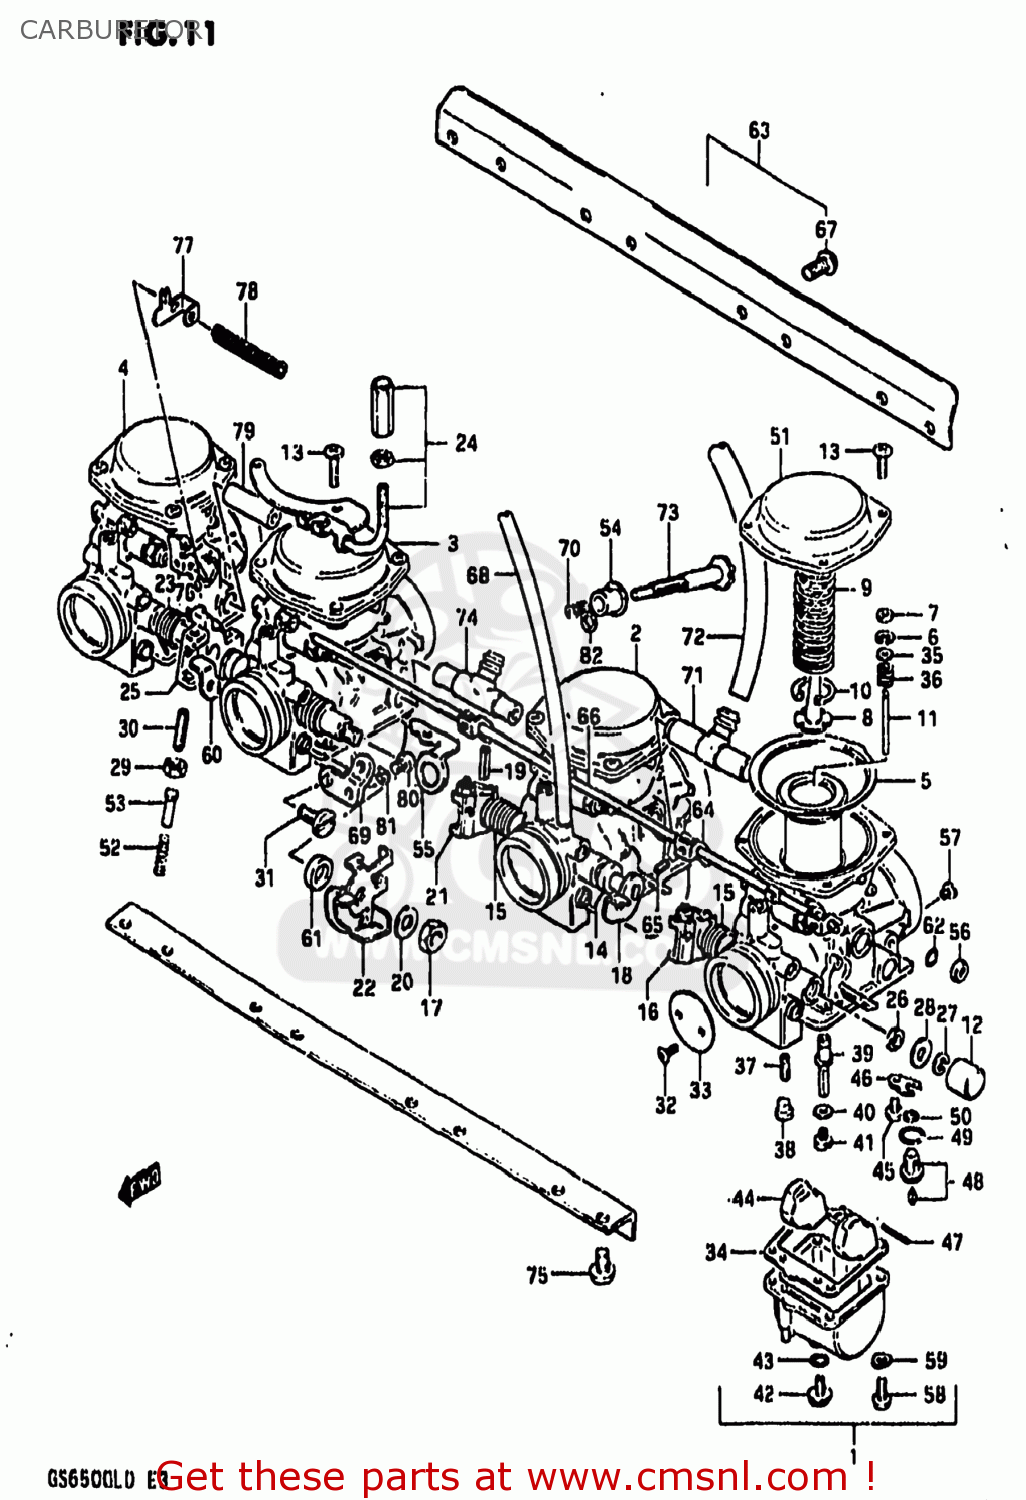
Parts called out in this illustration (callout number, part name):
1	CARBURETOR ASSEMBLY,LEFT
2	CARBURETOR ASSEMBLY
3	CARBURETOR ASSEMBLY
4	CARBURETOR ASSEMBLY
5	DIAPHRAGM
6	CLIP,NEEDLE
7	RING
8	HOLDER,GUIDE
9	SPRING
10	E RING
11	NEEDLE JET
12	CAP
13	SCREW
14	GASKET,THROTTLE SHAFT (NAS)
15	SPRING,THROTTLE SHAFT
16	SHAFT,THROTTLE
17	NUT 8MM
18	SHAFT,THROTTLE
19	PIN,THROTTLE SHAFT
20	WASHER
21	LEVER,THROTTLE SHAFT
22	LEVER ASSEMBLY,THROTTLE
23	SPRING,THROTTLE SHAFT
24	BRACKET,THROTTLE CABLE
25	SHAFT,THROTTLE
26	SEAL
27	E RING
28	GASKET,THROTTLE SHAFT (NAS)
29	NUT
30	SCREW
31	SCREW
32	SCREW
33	VALVE,THROTTLE (BUTTERFLY)
34	GASKET,FLOAT CHAMBER (NAS)
35	WASHER
36	SPRING
37	JET,PILOT(42.5)
38	PLUG,NEEDLE JET
39	JET,NEEDLE
40	WASHER,NEEDLE NOZZLE
41	JET,MAIN(110)
42	PLUG,DRAIN
43	GASKET (NAS)
44	FLOAT
45	SCREW 4X6
46	PLATE,NEEDLE VALVE FITING
47	PIN,FLOAT
48	VALVE ASSEMBLY,NEEDLE
49	O-RING,NEEDLE VALVE
50	FILTER
51	COVER,DIAPHRAGM
52	SPRING,THROTTLE SCREW
53	PIN,THROTTLE LEVER
54	BUSH
55	BRACKET,THROTTLE ADJUST
56	CAP,STARTER VALVE
57	JET
58	SCREW
59	LOCK WASHER
60	SHAFT,THROTTLE
61	WASHER
62	O RING
63	CARBURETOR ASSEMBLY
64	LEVER
65	SCREW
66	SHAFT,STARTER
67	SCREW
68	HOSE
69	BRACKET,THROTTLE ADJUST
70	SPRING
71	NIPPLE
72	HOSE
73	SCREW
74	NIPPLE,CARBURETOR
75	SCREW 6X12
76	LEVER,CHOKE CABLE
77	PLATE,CHOKE CABLE
78	SPRING,CHOKE CABLE
79	NIPPLE
80	SCREW
81	LOCK WASHER
82	WASHER
